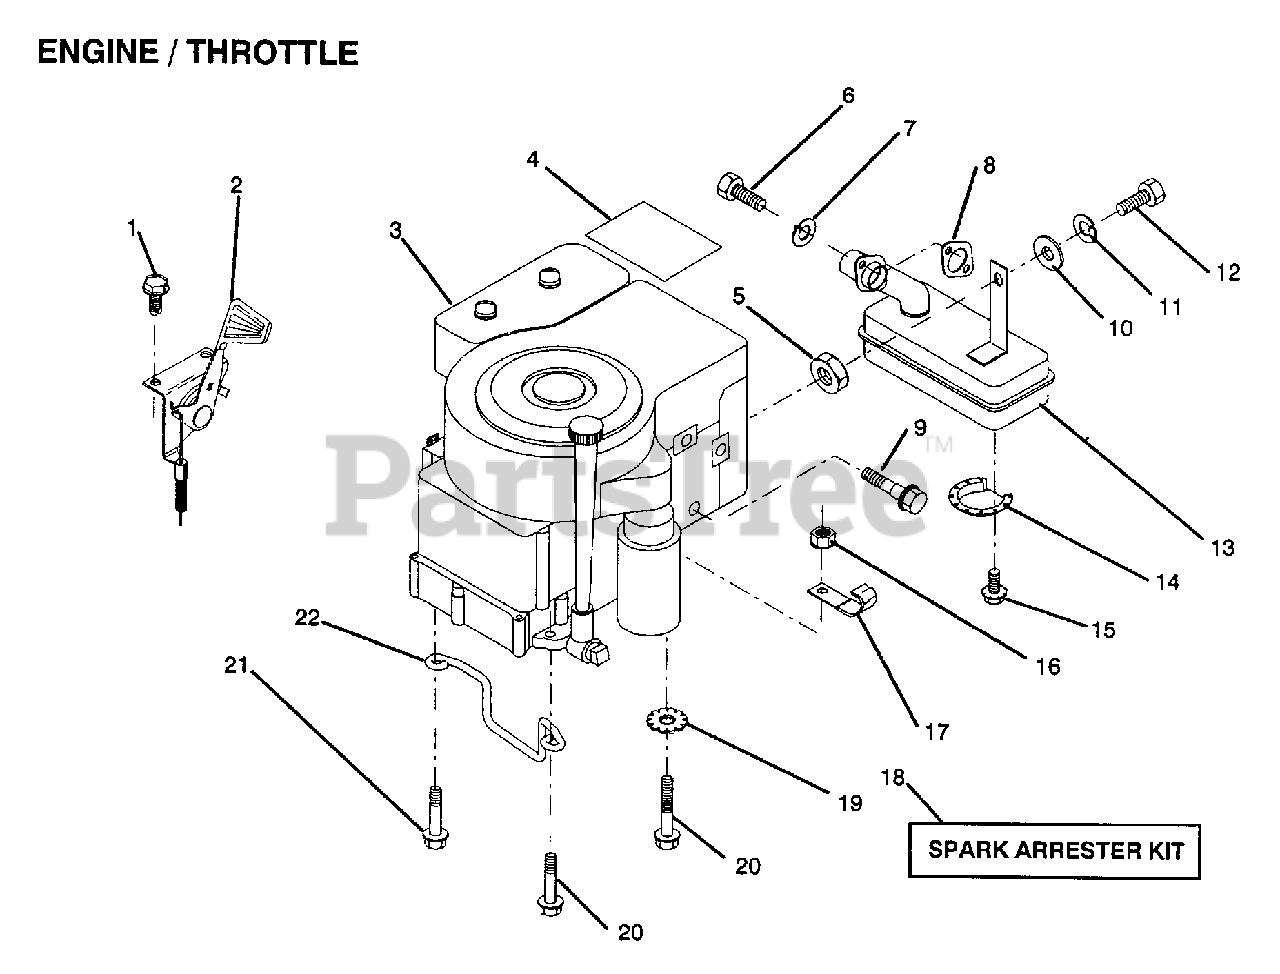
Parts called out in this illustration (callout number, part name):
1	SCREW
3	ENGINE BRIGGS AND STRATTON
4	DECAL.ENG.271967
5	NUT.HEX.5/16-18
6	SCREW
7	LOCKWASHER
9	BOLT T
11	LOCKWASHER
13	MUFFLER
14	DEFLECTOR.222573
16	NUT
17	CLIP T
19	LOCKWASHER
20	SCREW LT
21	SCREW LT
22	"KEEPER,DR BELT GR"
